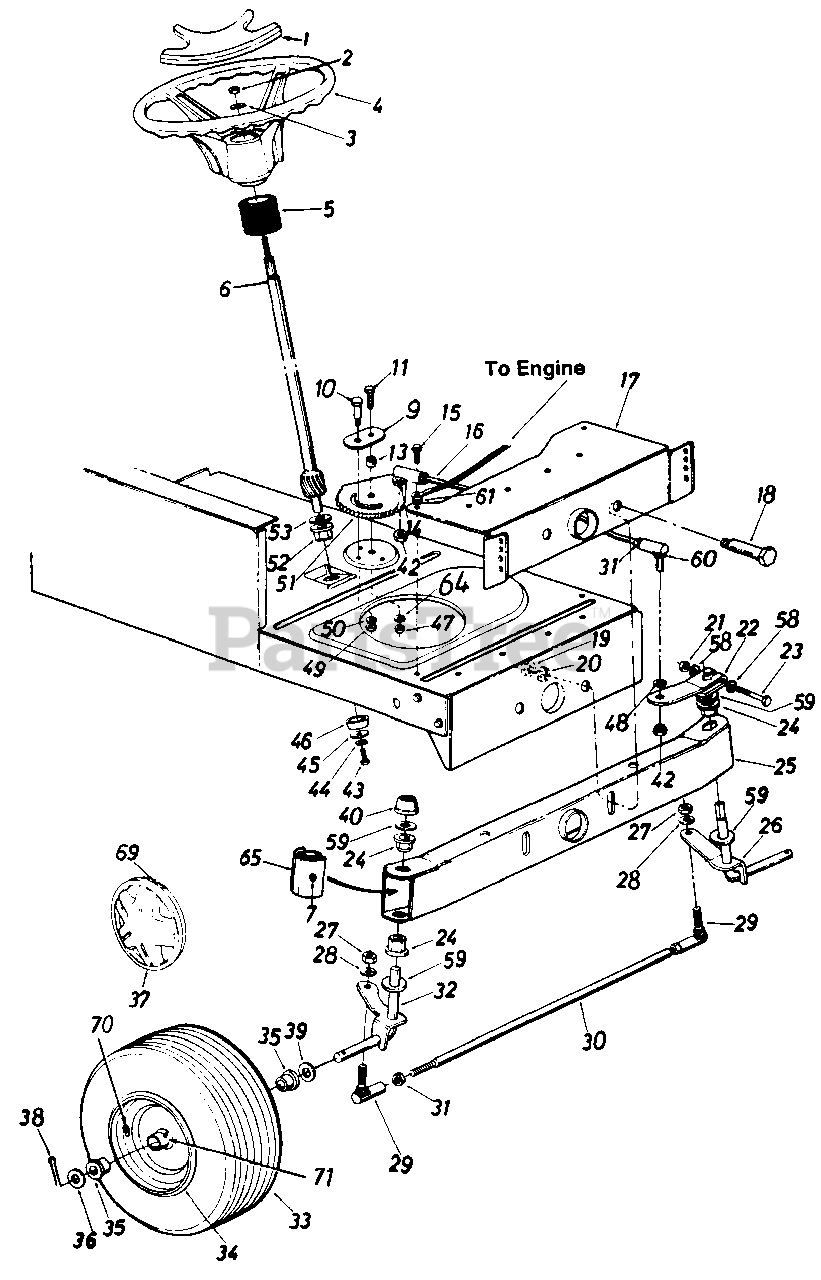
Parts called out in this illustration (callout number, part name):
1	Steering Wheel Cap
2	Hex L-Nut 5/16-24 Thd.
3	Belleville Wash. .345" I.D.
4	Steering Wheel
5	Steering Bellow - 9"
6	Steering Shaft Kit
7	Grease Fittings
9	Retainer Plate
10	Shoulder Bolt .437" Dia. x .35 Lg. 5/16-18 Thd.
11	Hex Bolt 3/8-24 x 1.0" Lg. (Grade 5)
13	Spacer .380" I.D. x .625" O.D. x .227
14	L-Wash. 3/8" I.D.
15	Hex Wash. Hd. Self-Tap Scr.
16	Steering Drag Link
17	Front Pivot Brkt.
18	Shoulder Bolt .498" Dia. x 2.04 Lg. 3/8-16 Thd.
19	Hex Nut 3/8-16 Thd.
20	L-Wash. 3/8" I.D.
21	Hex Cent. L-Nut 5/16-24 Thd.
22	Steering Arm Front Axle
23	Hex Bolt 5/16-24 x 2.00" Lg. (Grade 5)
24	Hex Fig. Brg. .632 I.D.
26	Front Axle Ass'y. - L.H.
27	Hex Nut 3/8-24 Thd.
28	L-Wash. 3/8" I.D.
29	Ball Joint 3/8-24 Thd.
31	Hex Jam Nut 3/8-24 Thd.
32	Front Axle Ass'y. - R.H.
36	Fl-Wash. .635 I.D. x 1.59" O.D
37	Front Wheel Hub Cap
38	Cotter Pin 1/8" Dia. x 1.25"
39	Fl-Wash. .640" I.D. x 1.24" O.D.
40	Push Cap 5/8" Dia. Rod
42	Hex Jam Nut 3/8-24 Thd.
43	Hex L-Bolt 5/16-18 x .62"
44	L-Wash. 5/16" I.D.
45	Fl-Wash. .33" I.D. x 1.25" O.D.
46	Spacer (Plastic)
47	Hex Cent. L-Nut 3/8-24 Thd.
48	L-Wash. 3/8" I.D.
49	Hex Cent. L-Nut 5/16-18 Thd.
50	L-Wash. 5/16" I.D.
51	Steering Gear Segment
52	Hex Flg. Brg. .634 I.D.
53	Fl-Wash. (Hardened)
58	Wave-Wash. .32" I.D. x .62" O.D.
59	Fl-Wash. (Hardened)
60	Drag Link Ball Joint 3/8-24 Thd.
61	Ext. L-Wash. 5/16" I.D.
64	Bell-Wash. .39" I.D. x 1.38" O.D
65	Pivot Bar End Cap
